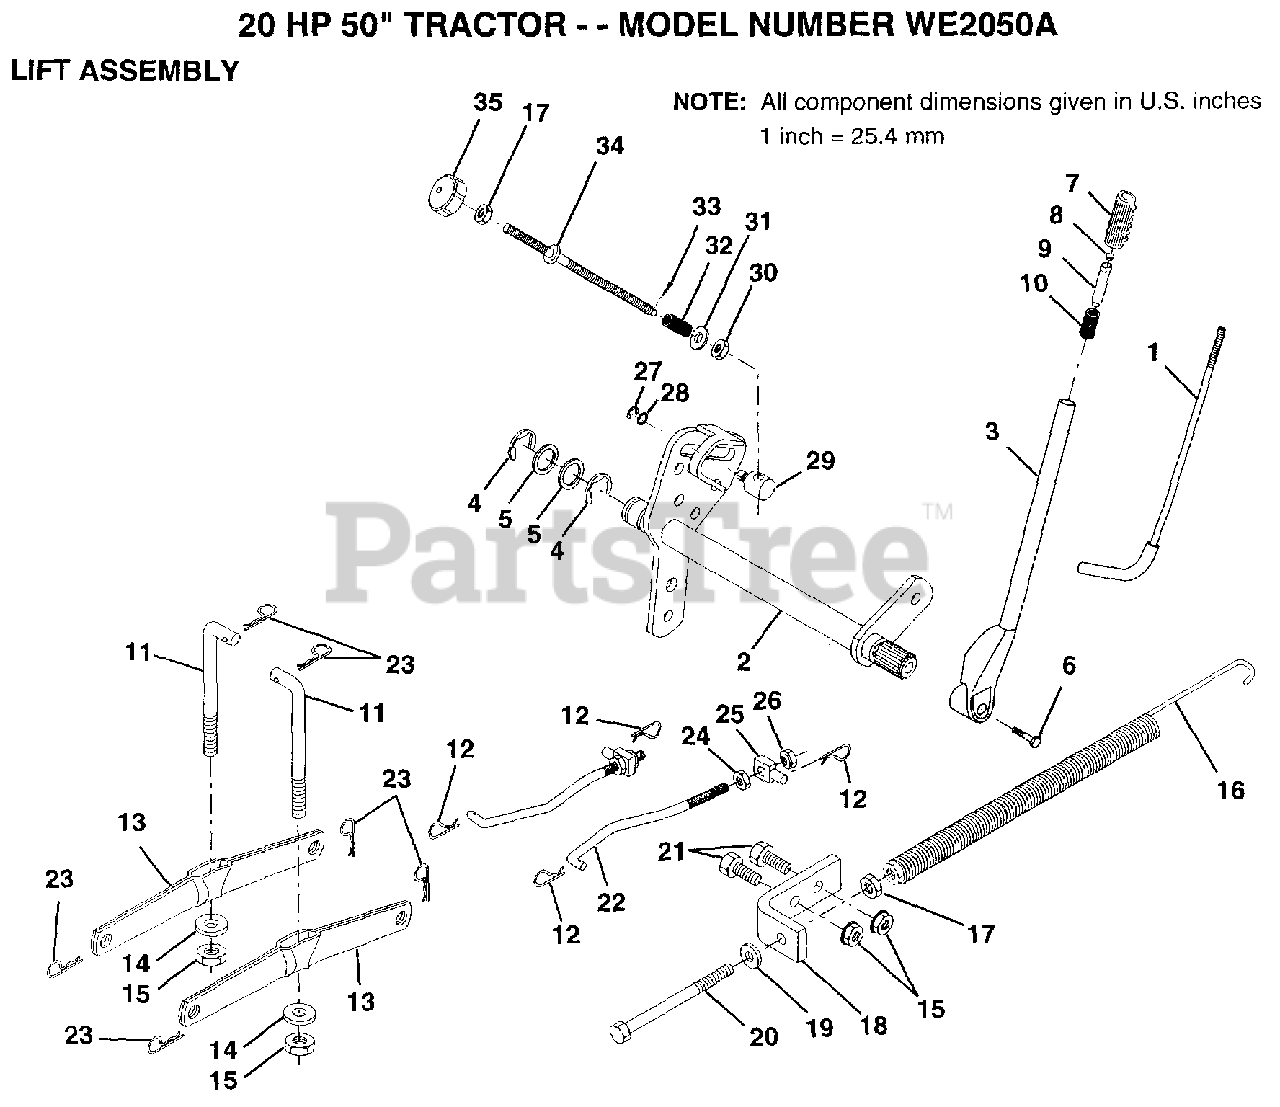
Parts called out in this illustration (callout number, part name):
1	LEVER ROD LT
4	E-RING
5	WASHER
6	"BOLT,HEX"
7	GRIP
10	SPRING T
12	RETAINER.SPRING
14	BEARING PVT LH
15	NUT
17	NUT
18	BRACKET SPRING AS
19	WASHER
20	BOLT-ADJ SPRING T
21	BOLT
22	LINK.FRONT
24	NUT
25	TRUNION
26	NUT.LK.W/WSH.1/2.
27	KLIP RING
28	WASHER
29	TRUNION LT
30	NUT T
31	WASHER
32	SPRING.COMP.INF.H
34	ROD.ADJ.LIFT
35	KNOB INF 3/8-16
